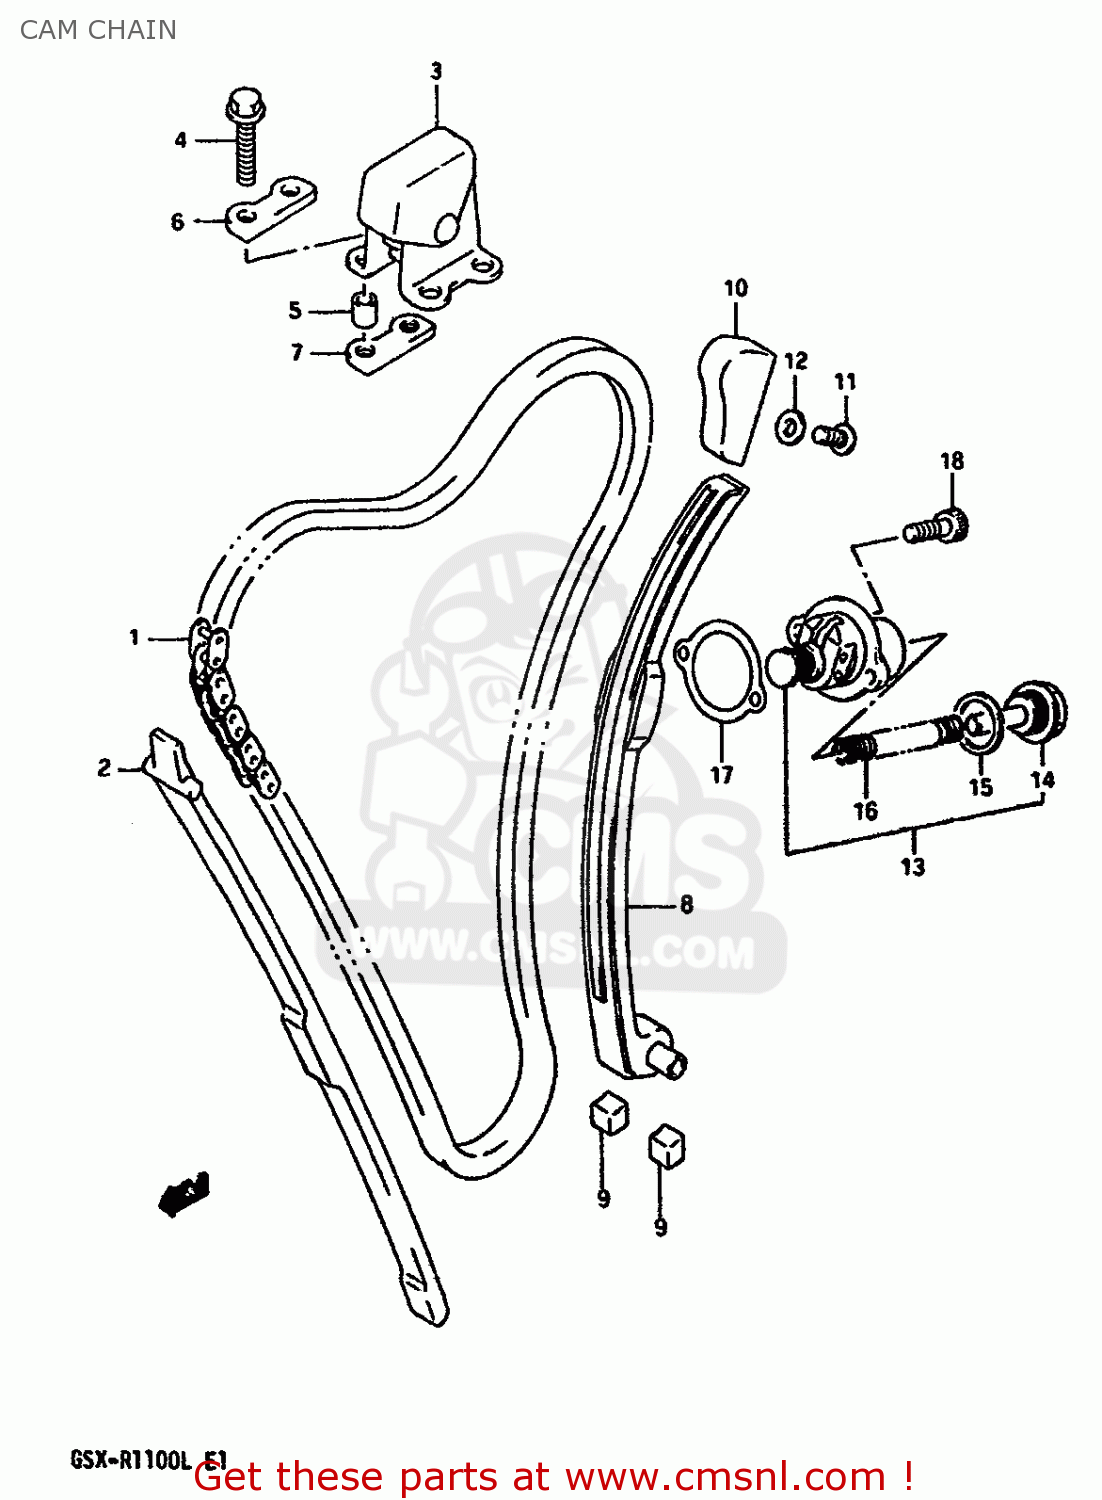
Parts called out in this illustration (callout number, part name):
1	CHAIN,CAMSHAFT DRIVE
2	GUIDE,CAM CHAIN NO.1
3	IDLER,CAM CHAIN
4	BOLT
5	SPACER (6,8X10X9.4)
6	CUSION,IDLER
7	CUSHION,IDLER
8	TENSIONER,CAM CHAIN
9	CUSHION,CAM CHAIN TENSIONER
10	GUIDE,CAM CHAIN NO.2
11	BOLT
12	GASKET(5.8X13X1.2) (NAS)
13	ADJUSTER ASSEMBLY,TENSIONER
14	PLUG
15	GASKET (NAS)
16	SPRING
17	GASKET,TENSIONER ADJUSTER (NAS)
18	BOLT
